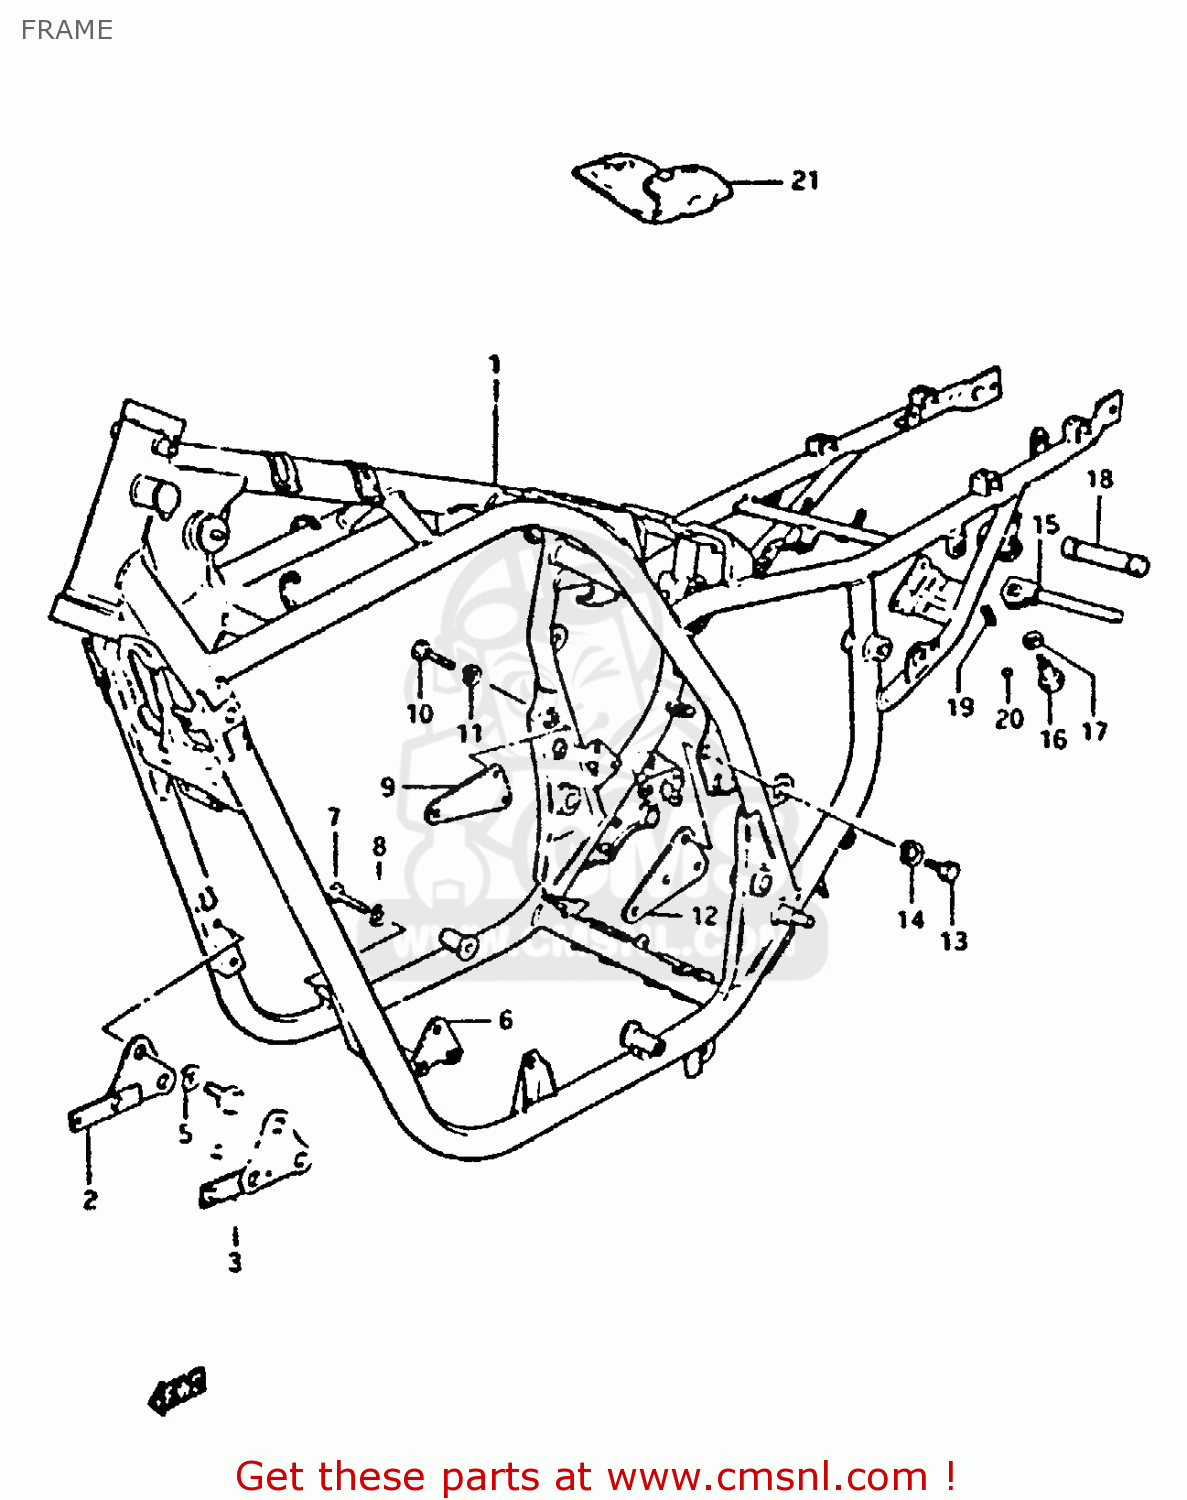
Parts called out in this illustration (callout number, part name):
1	FRAME (BLACK)
2	PLATE COMP,ENGINE MOUNTING
3	PLATE,ENGINE MOUNTING
4	BOLT
5	LOCK WASHER
6	PLATE,ENGINE MOUNTING
7	BOLT 8X50
8	LOCK WASHER
9	PLATE,ENGINE MOUNTING
10	BOLT 8X50
11	LOCK WASHER
12	PLATE,ENGINE MOUNTING
13	BOLT
14	LOCK WASHER
15	GRIP COMP,FRAME HANDLE
16	BOLT
17	WASHER
18	RUBBER
19	SPRING
20	BALL
21	TOOL SET
